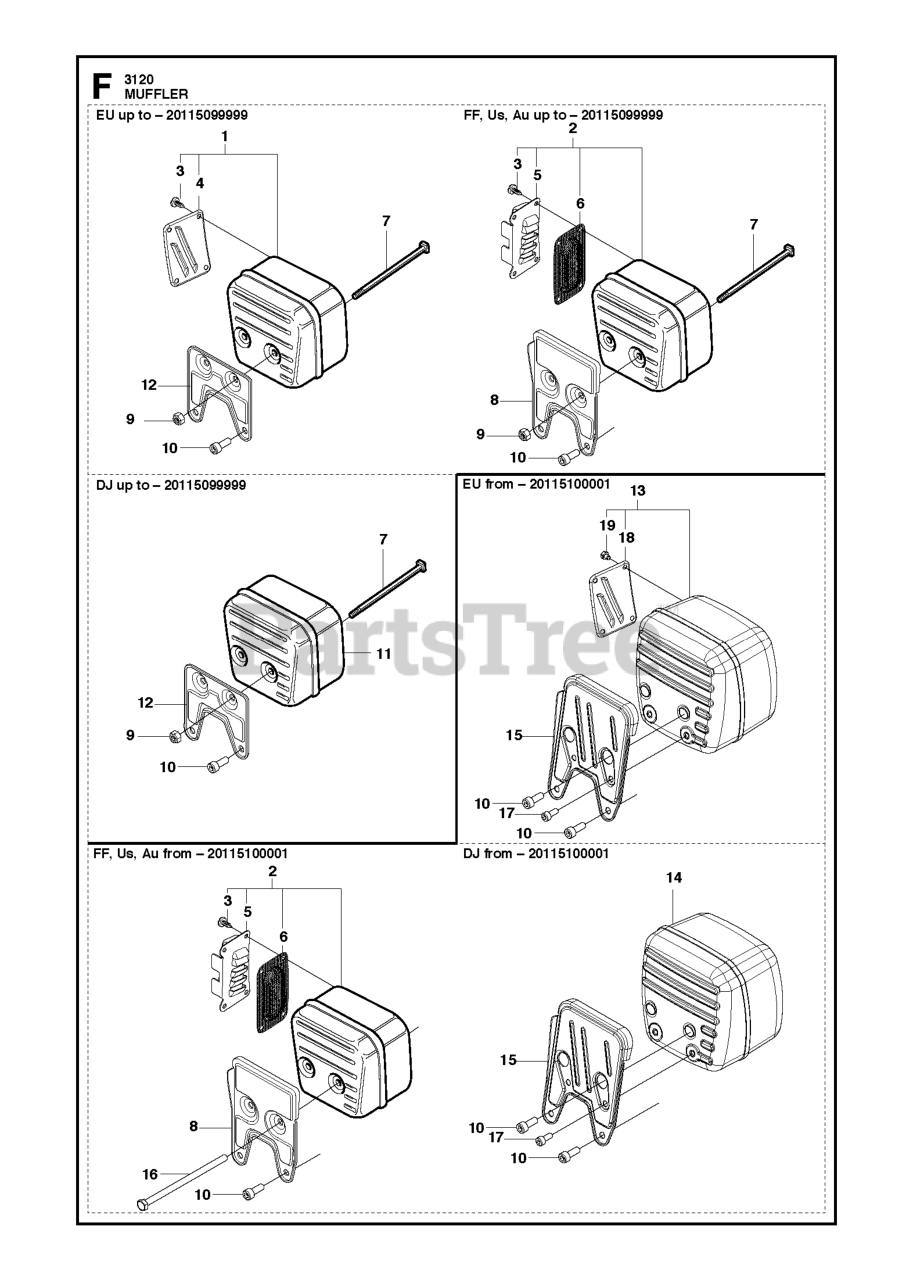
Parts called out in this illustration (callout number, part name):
2	MUFFLER
3	SCREW RXS B8X9.5
4	OUTLET
5	OUTLET
6	SCREEN
7	SCREW
8	SUPPORT
10	SCREW MC6S 6X16
11	MUFFLER ASSY
12	SILENCER SUPPORT
15	SILENCER SUPPORT
16	SCREW
17	SCREW MC6S 5X12
18	EXHAUST DUCT
19	SCREW EHHM
